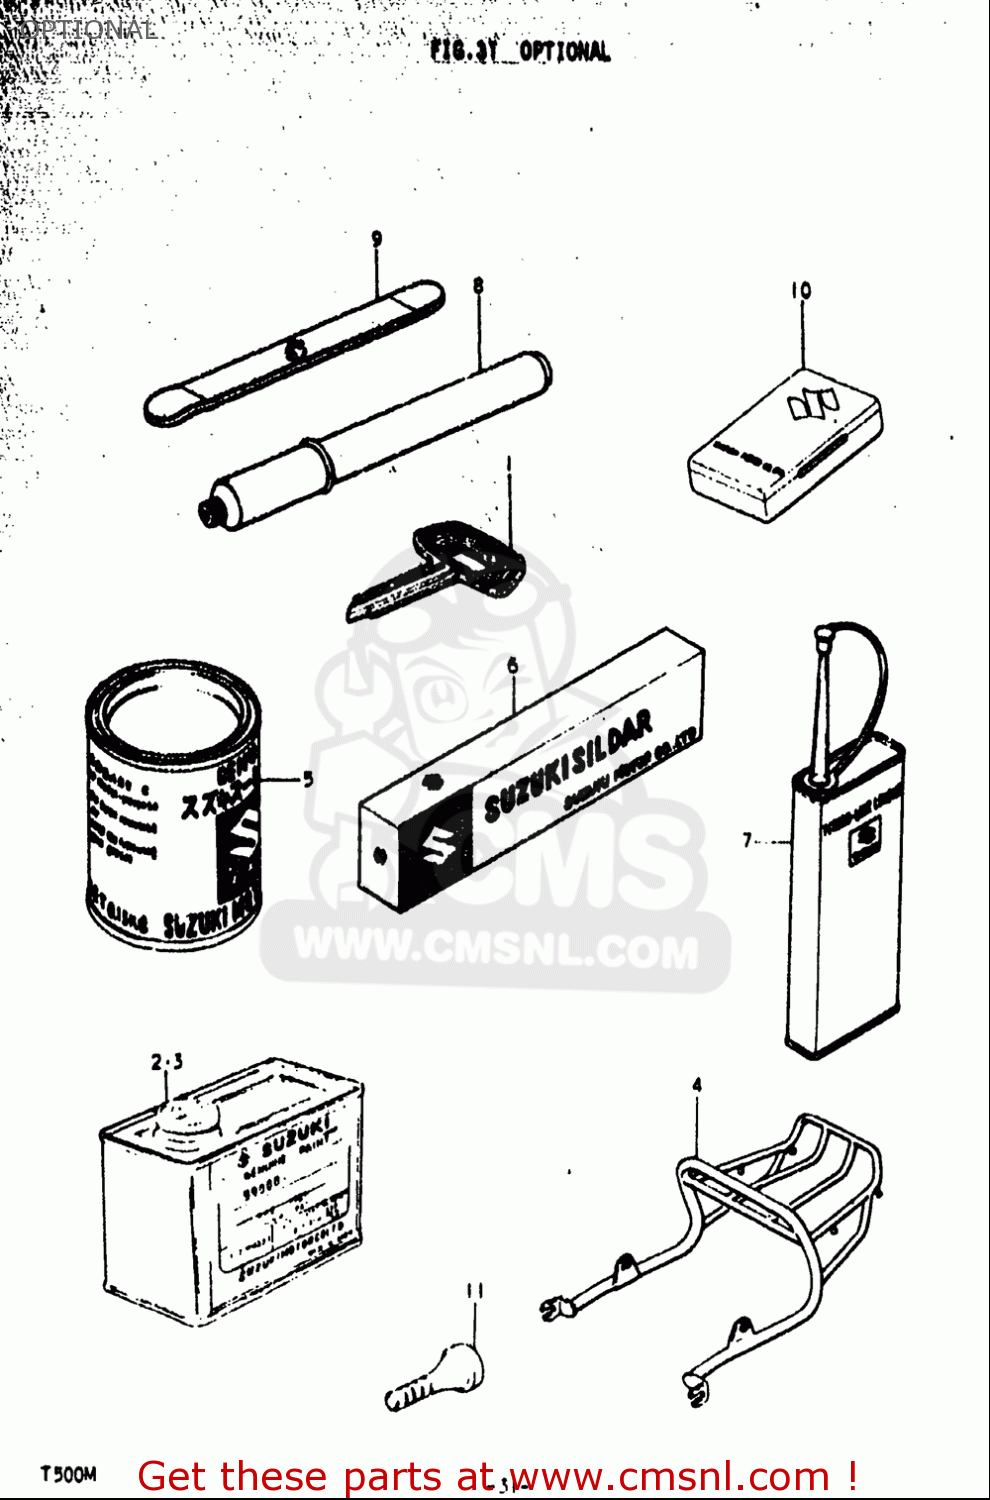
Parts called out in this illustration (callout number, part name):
1	KEY,BLANK
5	GREASE(C)EP2 LITHIUM 150G
7	THREAD LOCK NO.1401 CLEAR 200G
9	LEVER,TIRE
